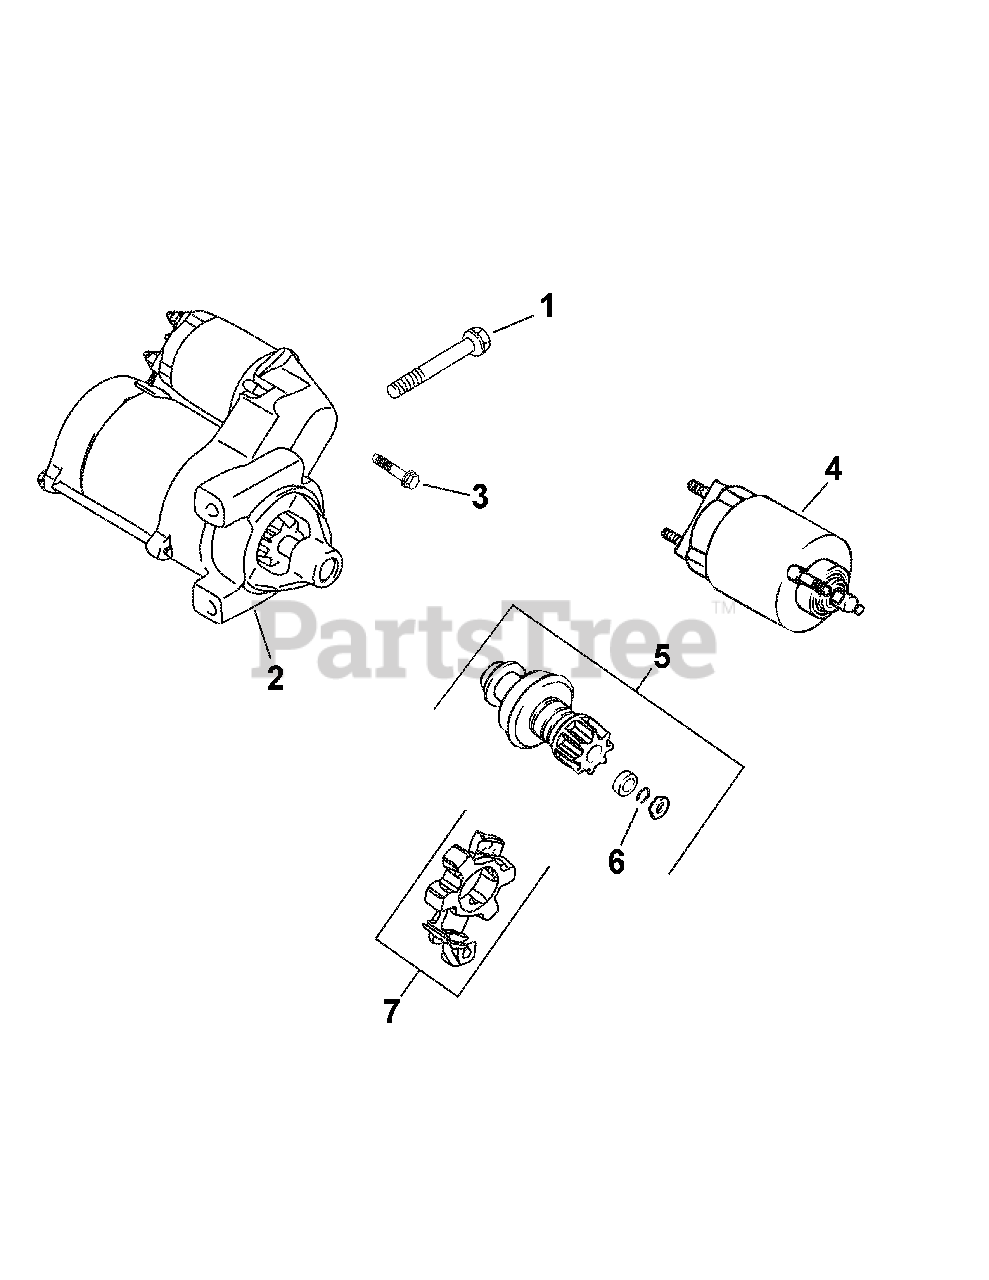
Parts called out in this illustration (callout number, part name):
1	Scr, hex flange M8x1.25x80
2	Starter, solenoid ass’y
3	Screw, external torx hd.
4	Kit, solenoid
5	Kit, starter pinion
7	Brush, holder
